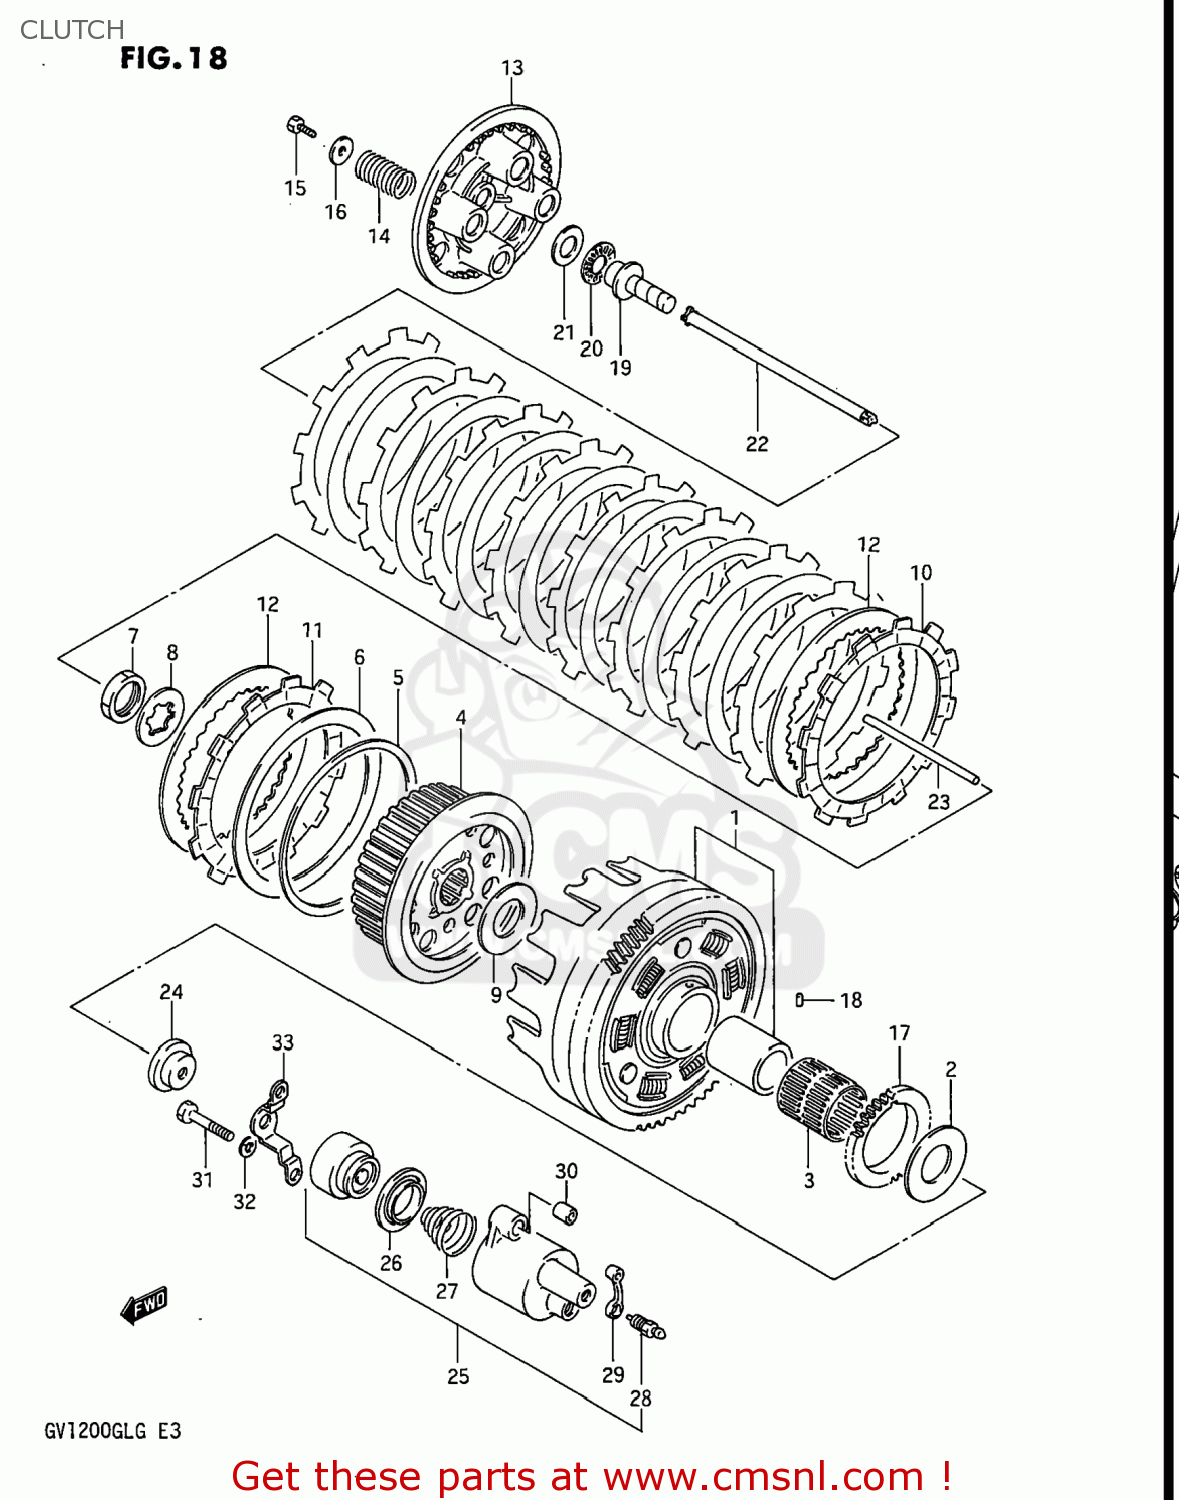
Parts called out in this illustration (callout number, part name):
1	GEAR ASSEMBLY,PRIMARY DRIVE
2	WASHER
3	BEARING(35X40X39.8)
4	HUB,CLUTCH SLEEVE
5	SEAT,WAVE WASHER(T:1.4)
6	WASHER
7	NUT
8	WASHER,LOCK
9	WASHER(25X50X2.5)
10	PLATE,CLUTCH DRIVE (NAS)
11	PLATE,CLUTCH DRIVE
12	PLATE,CLUTCH DRIVEN (NAS)
13	DISC,CLUTCH PRESSURE
14	SPRING
15	BOLT
16	WASHER
17	GEAR,OIL PUMP DRIVE
18	PIN(6X6)
19	PIECE,CLUTCH PUSH
20	BEARING(15X28X2)
21	WASHER
22	ROD,CLUTCH PUSH
23	ROD,CLUTCH PUSH
24	OIL SEAL
25	CYLINDER,CLUTCH RELEASE
26	CUP,CLUTCH CYLINDER
27	SPRING,CLUTCH CYLINDER
28	BLEEDER
29	CAP,BLEEDER
30	PIN
31	BOLT ,6X35
32	WASHER,LOCK
33	PLATE,CLUTCH PUSH ROD
